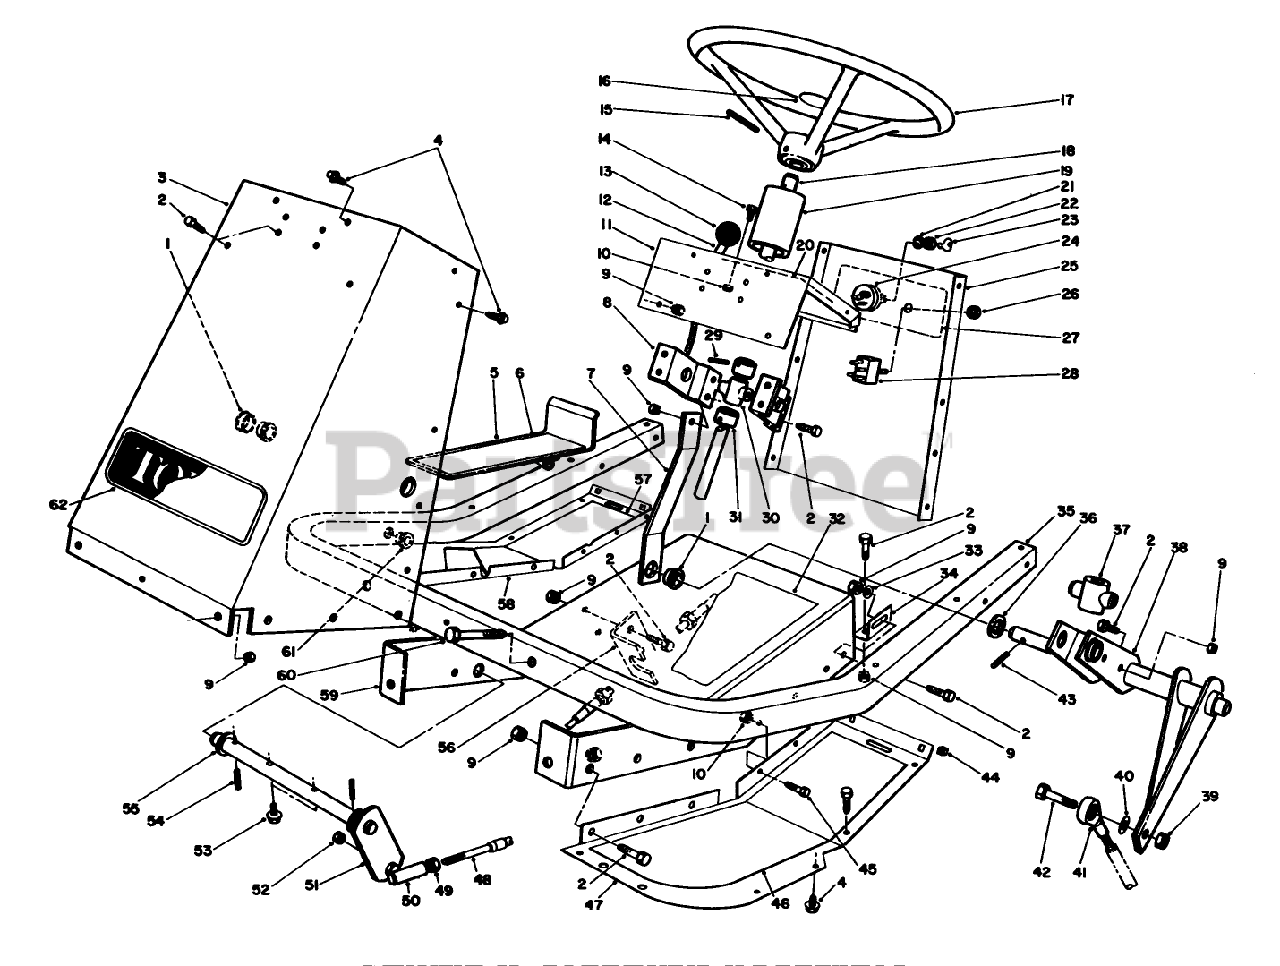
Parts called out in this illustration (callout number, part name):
1	BEARING-FLANGE
2	SCREW-HH
4	SCREW-HHFTF
8	BRG SUPT BRKT
9	NUT-LOCK, NI
10	NUT-LOCK, NI
12	CONTROL-CHOKE,THROTTLE
14	SCREW-HH
15	PIN-ROLL
16	STEERING WHEEL CAP
19	STRG. SHAFT COVER
20	THROTTLE DECAL
21	WASHER-LOCK
22	NUT-HEX
24	SWITCH
29	PIN-SPRING
31	STRG SHAFT COLLAR
33	WASHER-PLAIN
34	TUNNEL BRKT
36	WASHER-THRUST
37	STEER.SHAFT FOLLOWER
39	NUT-HEX
40	WASHER-FLAT
41	BALL JOINT LH
42	SCREW-HH
43	PIN-ROLL
44	NUT-RETAINED
45	SCREW-HH
49	NUT-JAM
50	JOINT-BALL
52	NUT-LOCK
53	SCREW-HWH
54	PIN-SPRING
55	WASHER-FLAT
57	FOOT REST PAD RH
60	SCREW-HH
61	BUSHING-FLANGE
